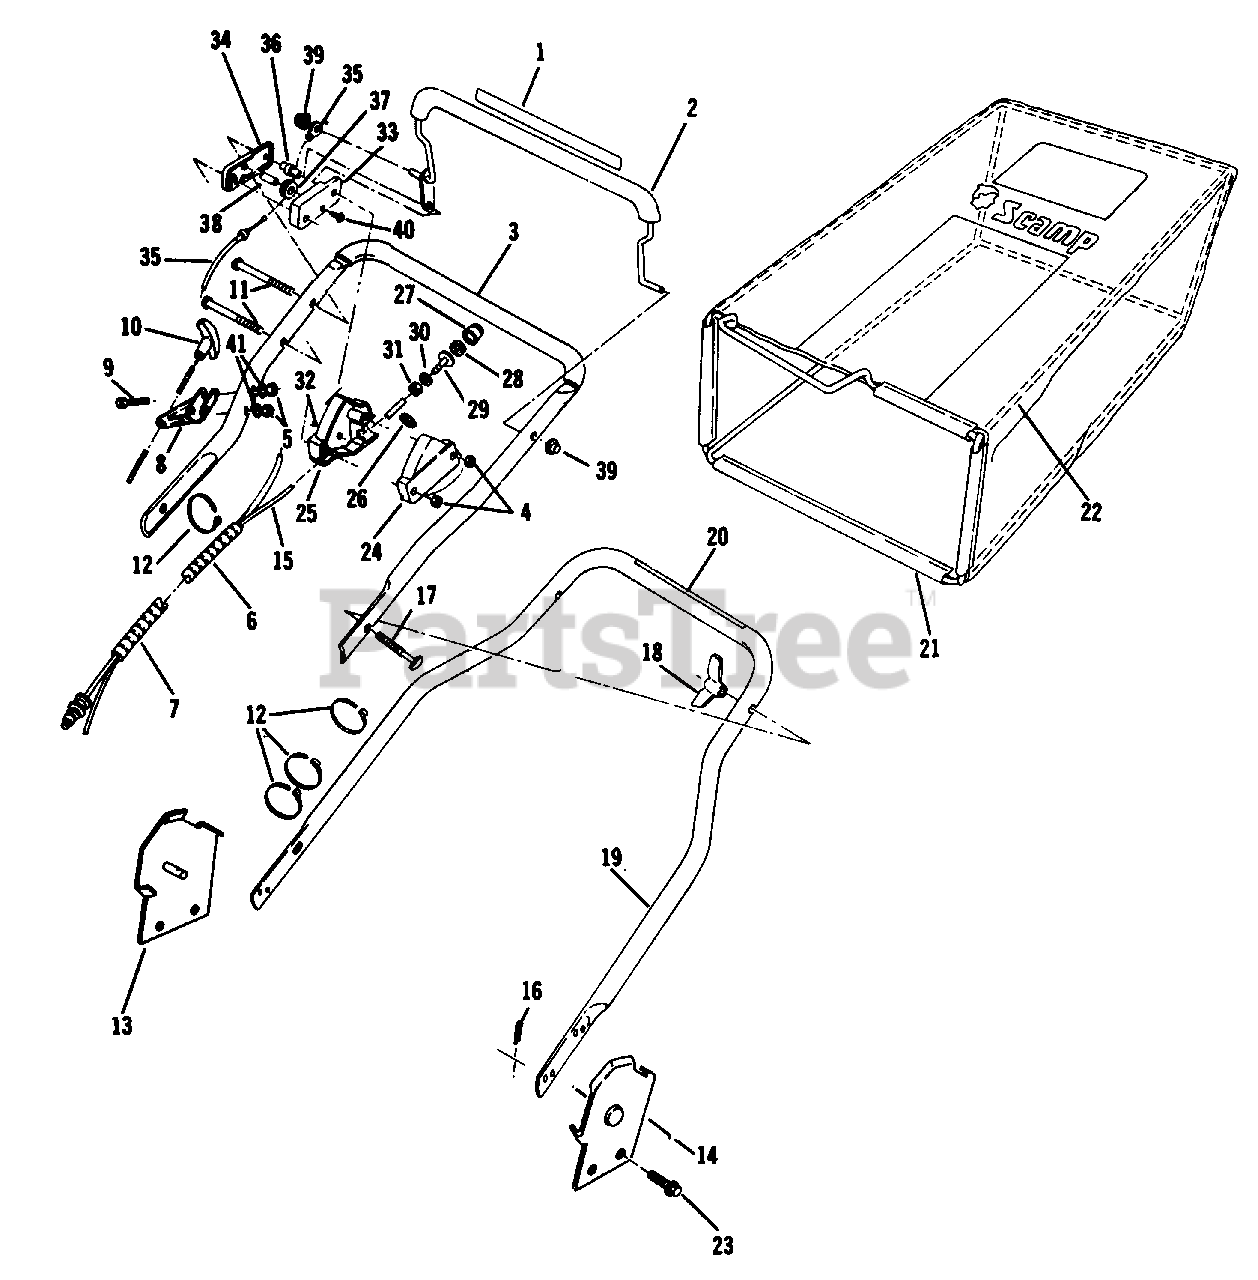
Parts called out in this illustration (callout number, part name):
1	Decal-Engine/Blade Control
2	Control Lever and Cable Ass'y
3	Top Handle and Grip Assembly
4	Locknut-Hex
5	Locknut
6	Spiral Tubing
7	Spiral Tubing
8	Rope Guide Assembly
9	Screw-Truss Head
10	Handle-Starter
12	Tie Strap
13	Bracket-Handle-R.H.
14	Bracket-Handle-L.H.
16	Hairpin
17	Screw-Folding Handle
18	Knob-Folding Handle
19	Handle-Bottom
20	Decal-Starting Inst.
21	Bag Assemble
22	Frame-Support-Bag
23	Screw-Bracket Handle to Hsg.
24	Console Left
25	Console Right
26	Plug Button
27	Primer Bulb
29	Primer Base
31	Locknut
32	Screw Truss Head
33	Control Case-Inner
34	Control Case-Outer
35	Control Cable Assembly
37	Pulley
39	Push Nut
40	Screw Truss Head
